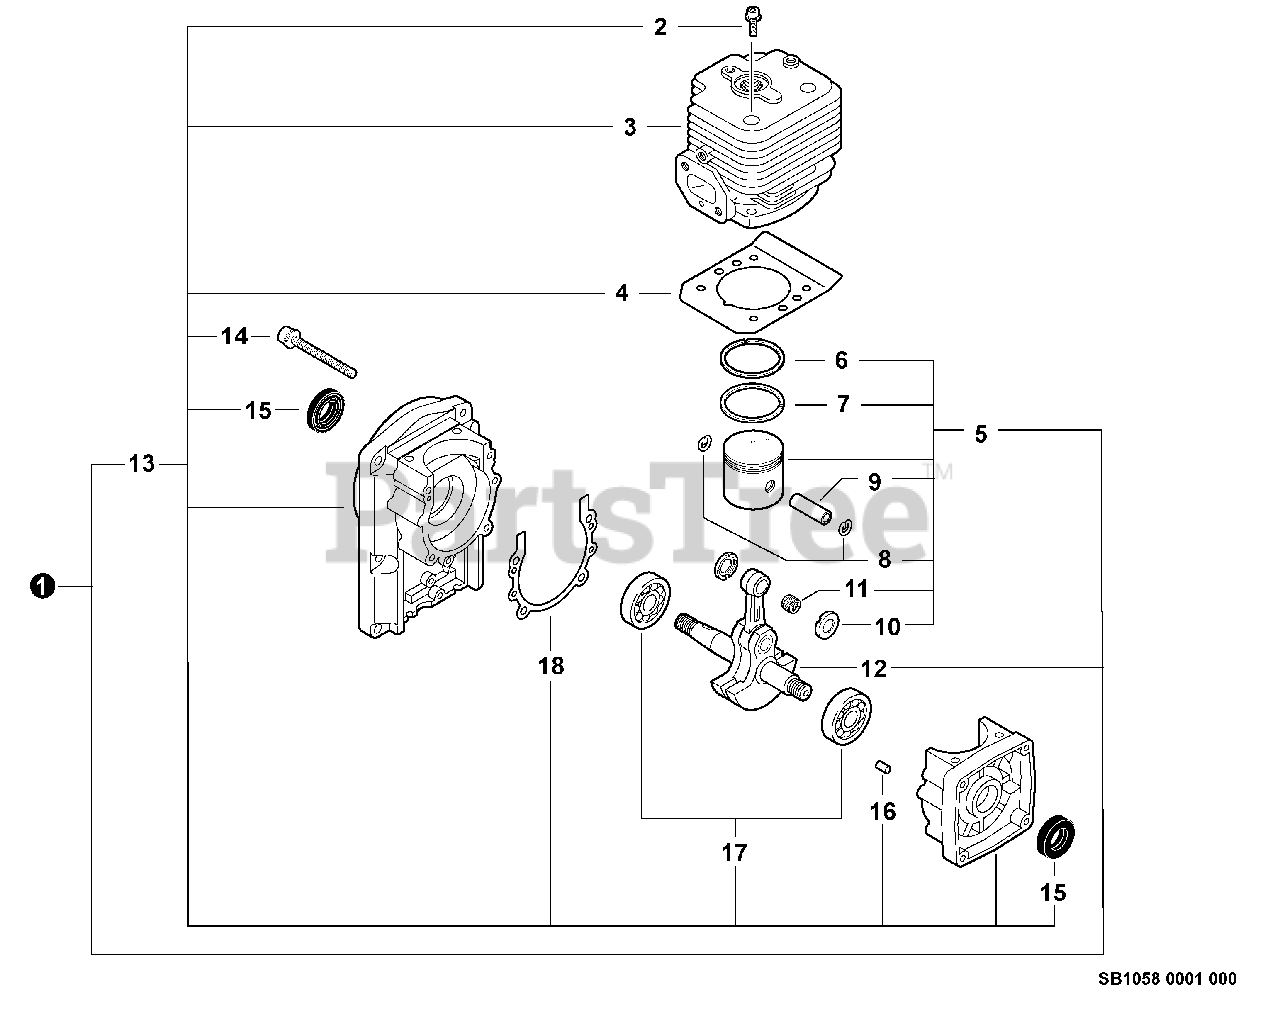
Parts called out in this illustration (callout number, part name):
1	SHORT BLOCK
2	BOLT 5×22
3	CYLINDER
4	GASKET, CYLINDER
5	PISTON KIT
6	RING, PISTON
7	RING, PISTON
8	RING, SNAP 8
9	PIN, PISTON
10	WASHER, THRUST
11	BEARING, NEEDLE 10
12	CRANKSHAFT ASSY
13	CRANKCASE KIT
14	BOLT M5×35
15	SEAL, OIL 15
16	PIN, LOCATING 4
17	BEARING, BALL 6302
18	GASKET, CRANKCASE
